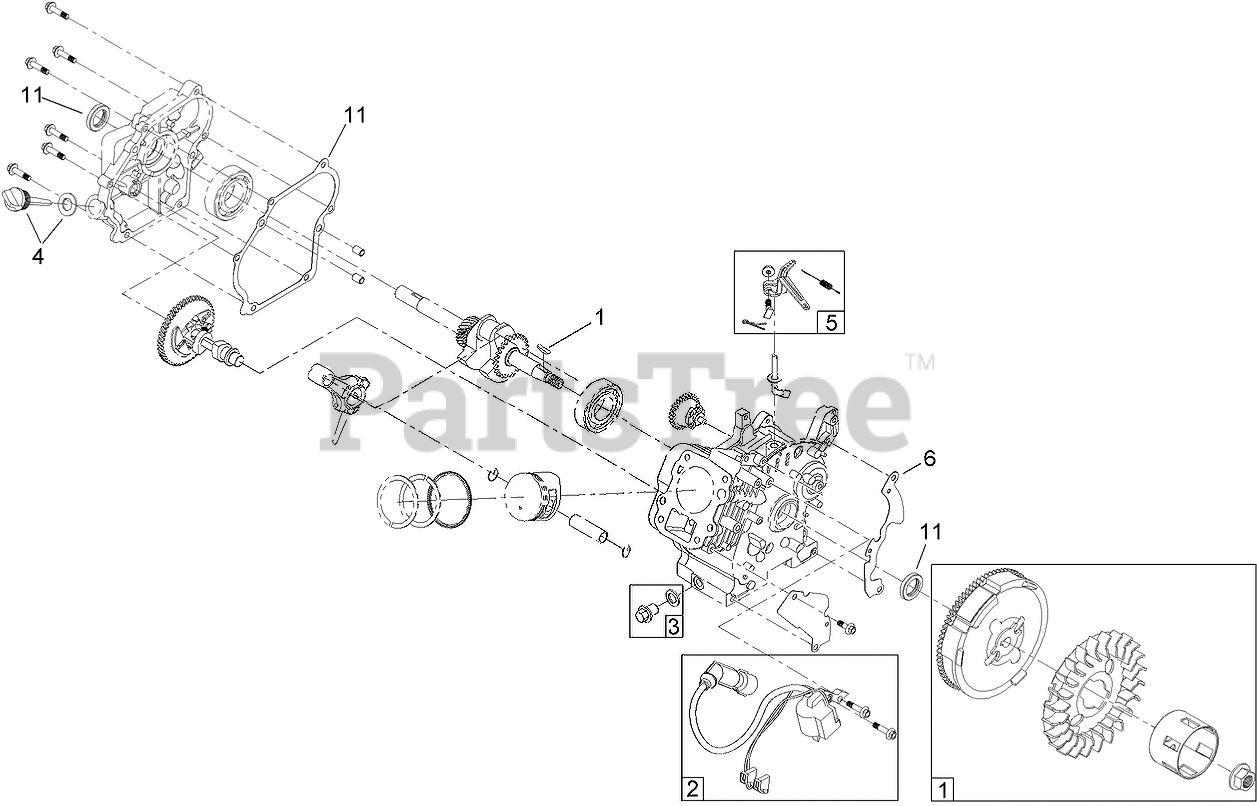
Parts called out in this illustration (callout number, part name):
1	FLYWHEEL KIT
2	IGNITION KIT
3	DRAIN PLUG KIT
4	DIPSTICK AND O-RING KIT
5	GOVERNOR KIT
6	BLOWER SHROUD KIT
11	GASKET, SEAL AND O-RING KIT
